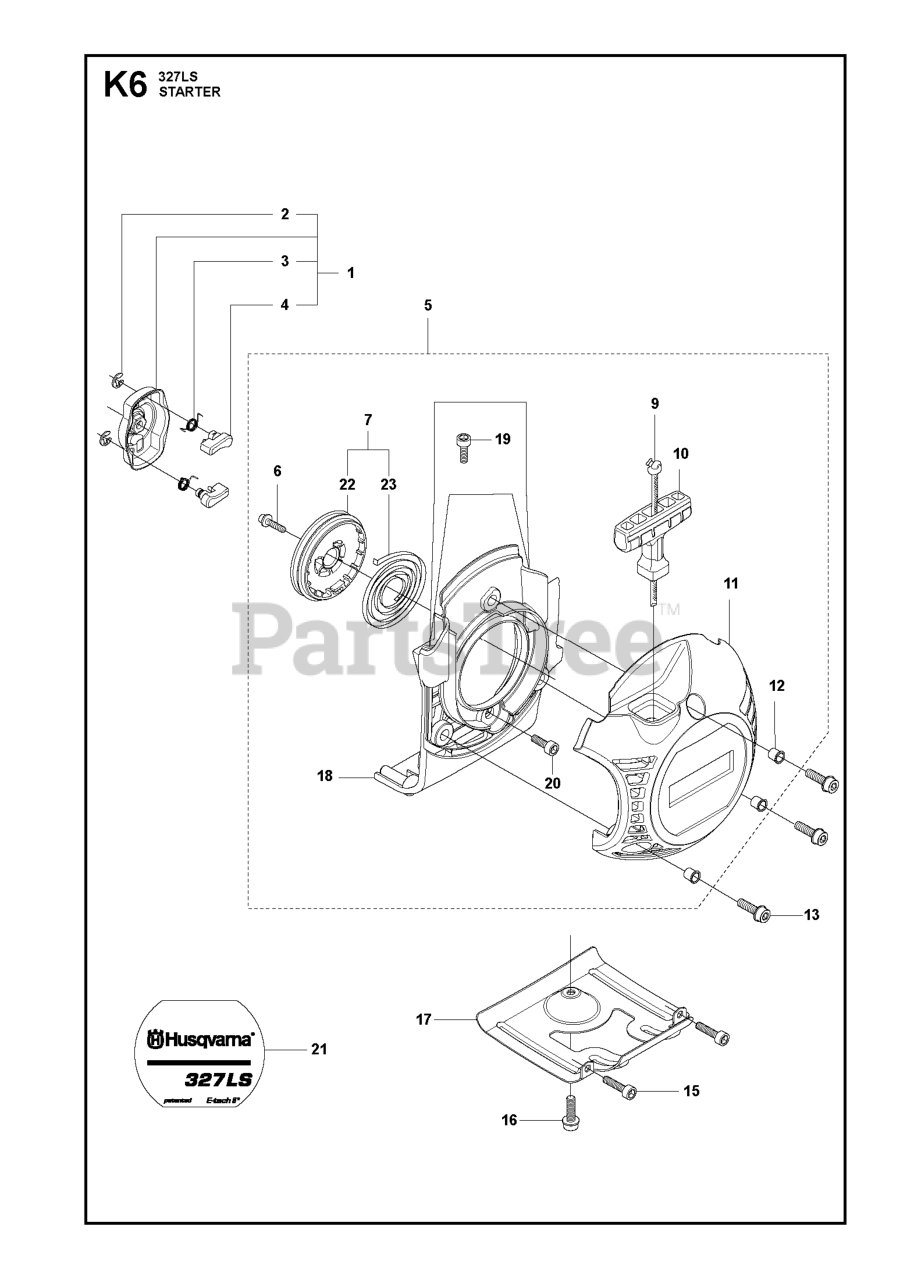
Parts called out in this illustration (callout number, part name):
1	STARTER PAWL BRIDGE
4	STARTER PAWL
5	STARTER ASSY
7	STARTER PULLEY
8	SPACING SLEEVE
9	STARTER ROPE
10	STARTER HANDLE
11	STARTER HOUSING
12	SPACING SLEEVE
13	SCREW
16	SCREW
18	BRACKET ASSY
19	SCREW IHSCFMO
22	STARTER PULLEY
23	STARTER SPRING
